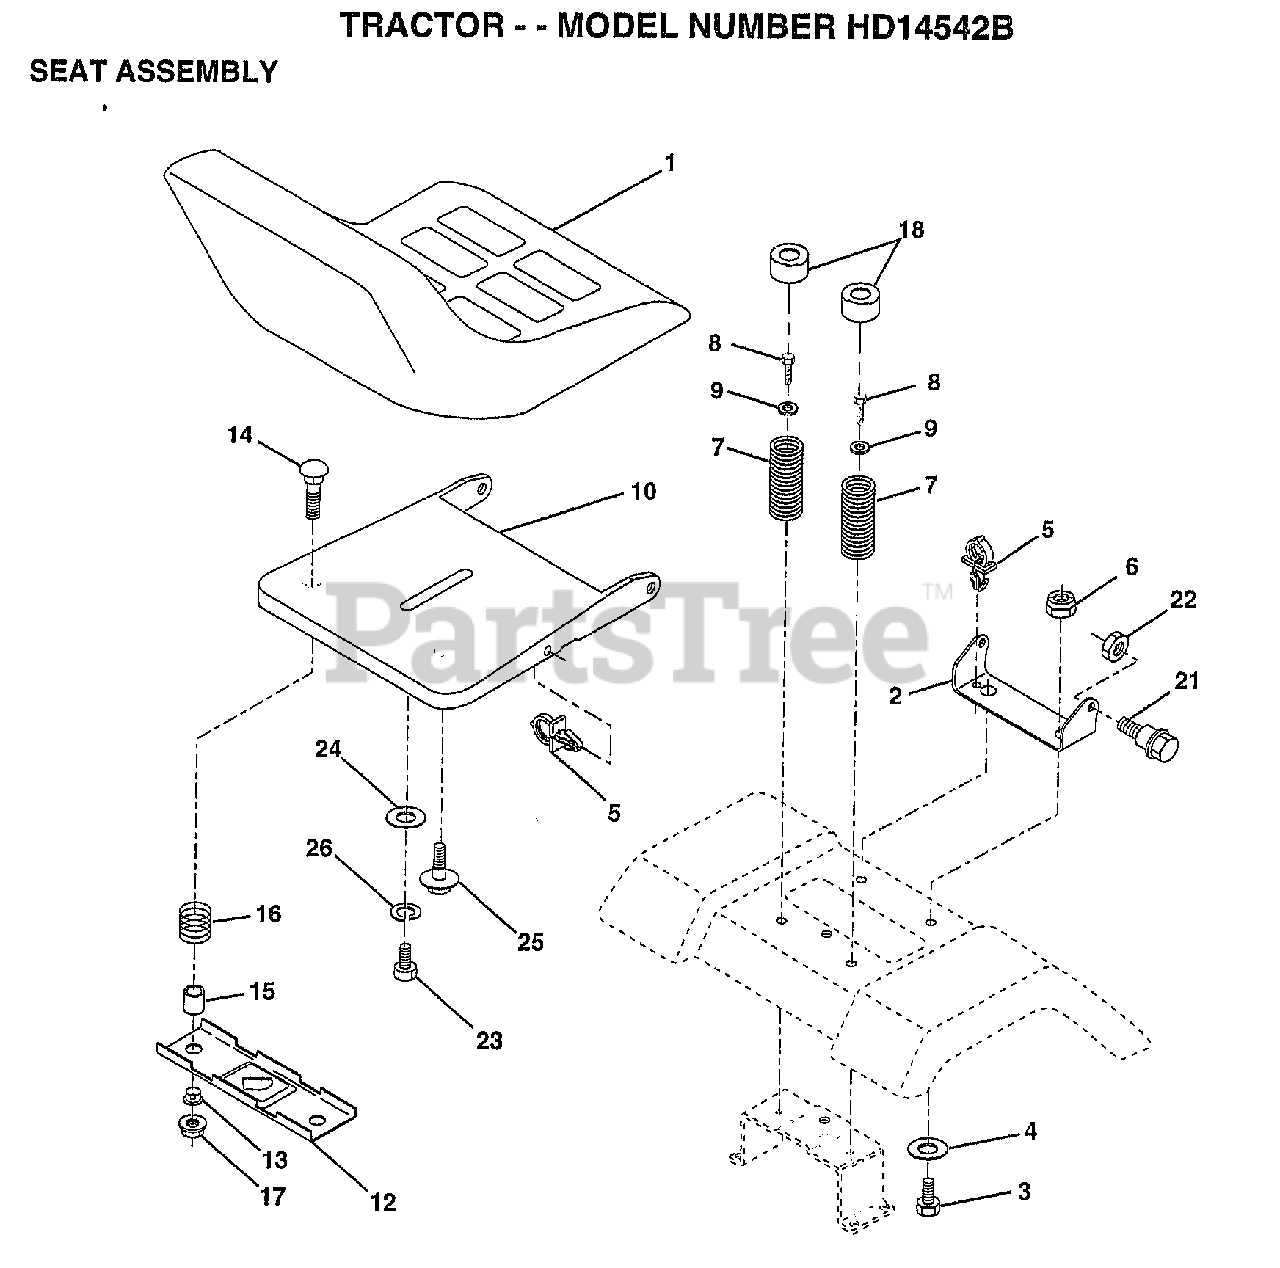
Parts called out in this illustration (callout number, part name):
1	SEAT
2	BRACKET PVT SEAT
3	BOLT
4	WASHER PM
5	CLIP.PUSH-IN.HING
6	NUT
7	SPRING COMPRESSIO
8	SCREW GTV
9	WASHER
10	PAN-SEAT
12	BRKT SWITCH
13	BUSHING
14	BOLT-RD HD SQ NK
15	SPLIT SPACER
16	SPRING
18	CAP SPRING
21	"BOLT,SHOULDER"
22	NUT
23	BOLT
24	WASHER
25	"BOLT,SHOULDER"
26	LOCKWASHER
